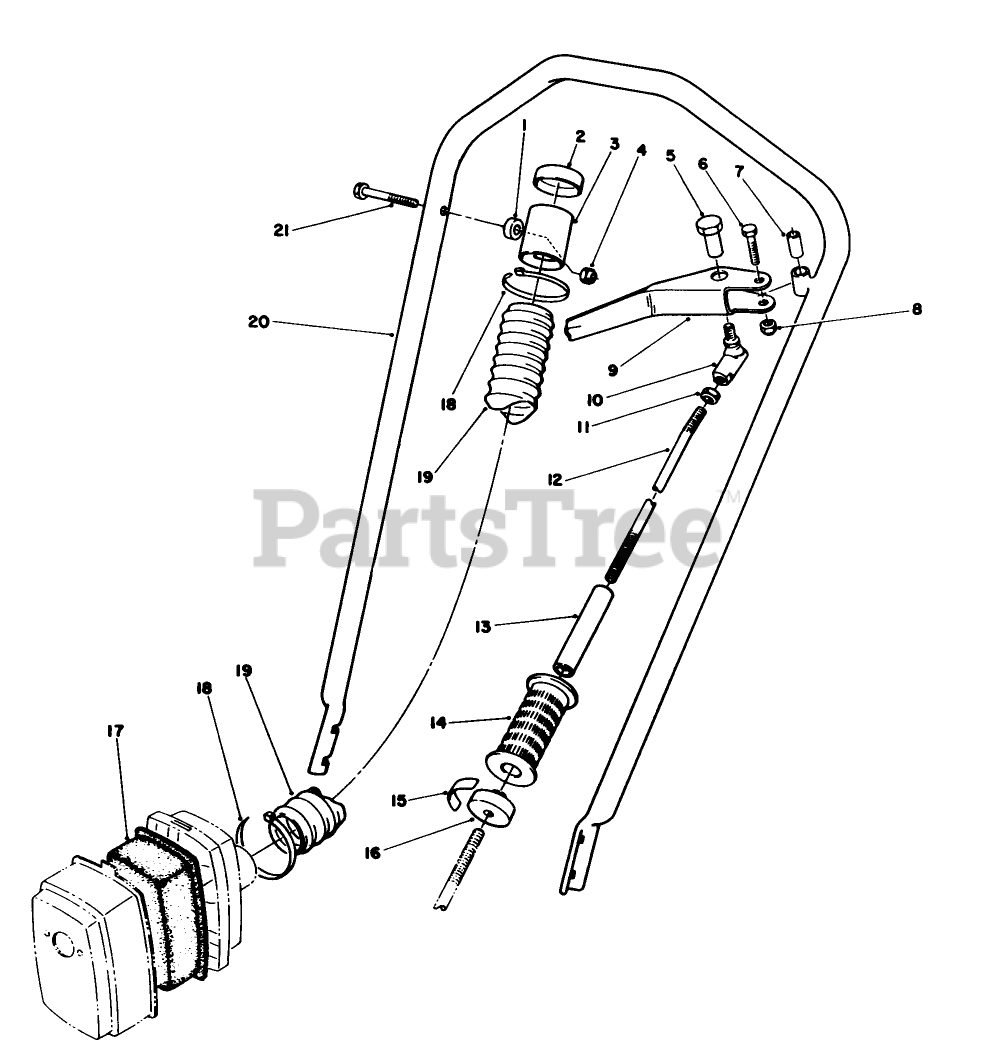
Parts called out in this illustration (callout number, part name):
2	BLACK CAPLUG
4	NUT-HEX
6	SCREW-HH
8	NUT-LOCK, NI
10	BALL JOINT
11	NUT-HJ
18	TIE-CABLE
21	SCREW-HH
